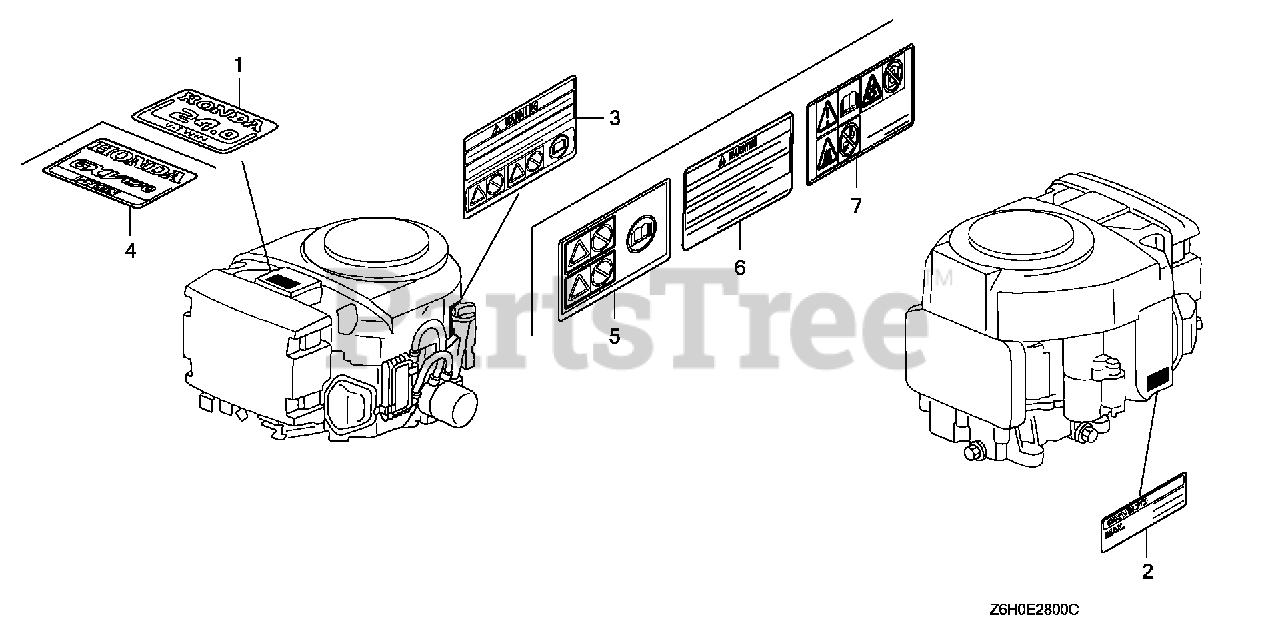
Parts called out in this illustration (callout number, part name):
1	EMBLEM (24.0)
1	EMBLEM (GX670)
2	LABEL, SPECIFICATION (GXV670)
3	MARK, OPERATOR CAUTION (ENGLISH)(MADE IN JAPAN)
4	MARK, EMBLEM (GXV670)
5	MARK, OPERATOR CAUTION (PICTOGRAPH)(MADE IN JAPAN)
6	MARK, OPERATOR CAUTION (ENGLISH)(MADE IN JAPAN)
